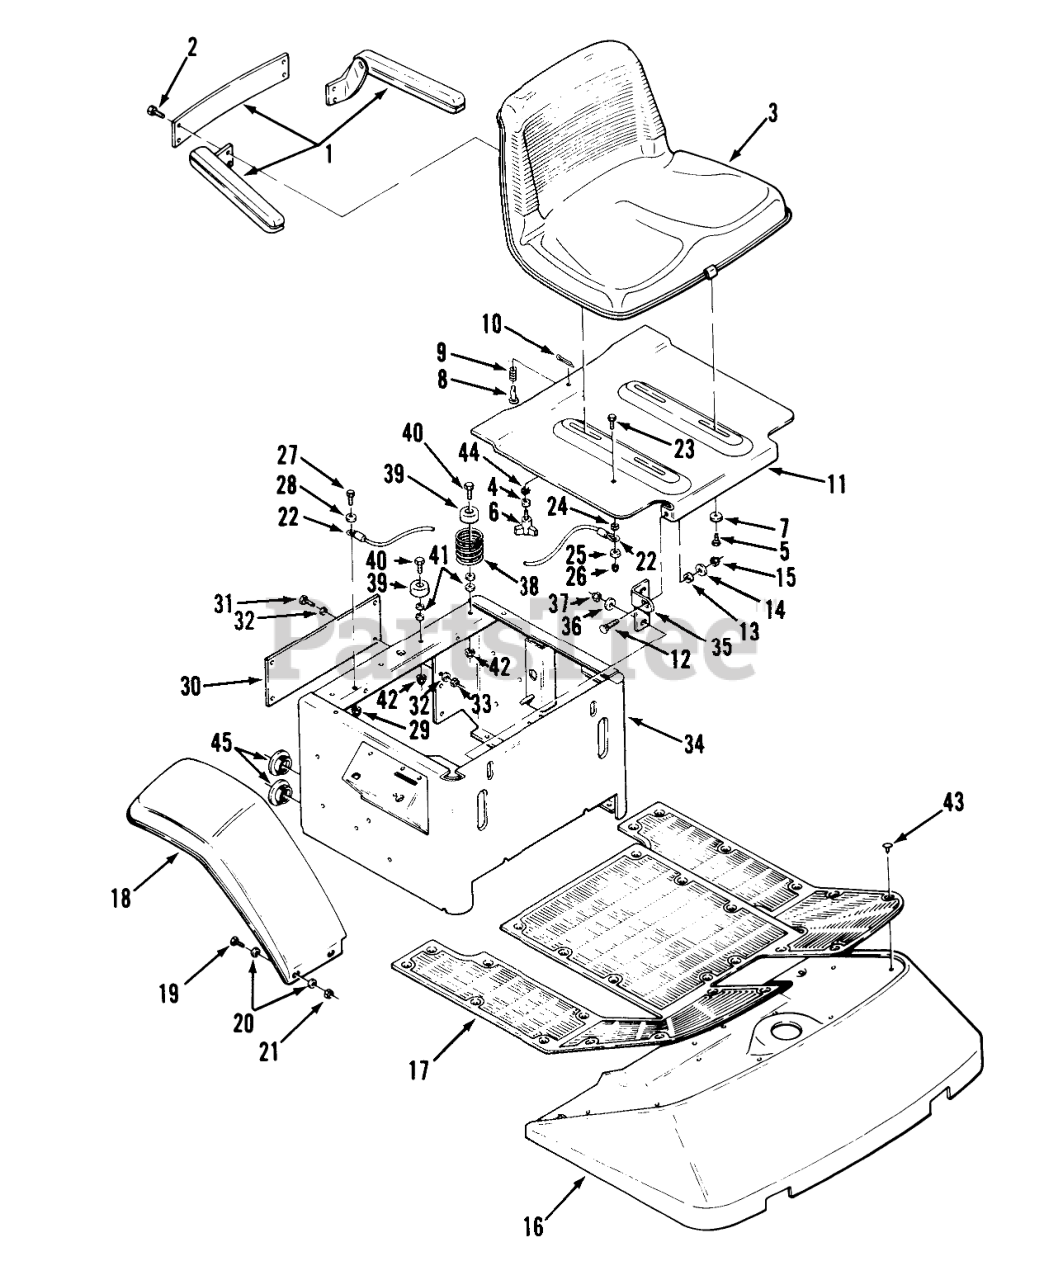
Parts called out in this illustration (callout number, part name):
1	KIT-ARMREST
2	Bolt
3	Seat
4	WASHER 5/16 SAE
5	BOLT 5/16-18X5/8
7	WSHR .312X1.0X11 GA
9	SPRING-COMPRESSION
10	Cotter Pin
11	PLATE SEAT PIVOT R
12	Bolt
13	SPACER
14	Washer
15	NUT
16	Floor Pan
17	Black Mat
18	Fender RH
19	Bolt
21	Nut
22	Cable
23	Bolt
24	Nut
25	Collar
26	Nut
27	Bolt
28	Collar
29	Nut
30	COVER-SEAT BOX R
31	Bolt
32	WASHER 5/16 SAE
33	Nut
34	Seat Support
35	Seat Pivot Bracket RH
36	Washer
37	NUT
38	SPRING-SEAT NYLON
39	BUMPER
40	Bolt
41	Collar
42	Nut
43	RIVET .25 PLASTIC
44	LOCKWASHER INT EXT
45	BUSHING-NYLON 1.500
